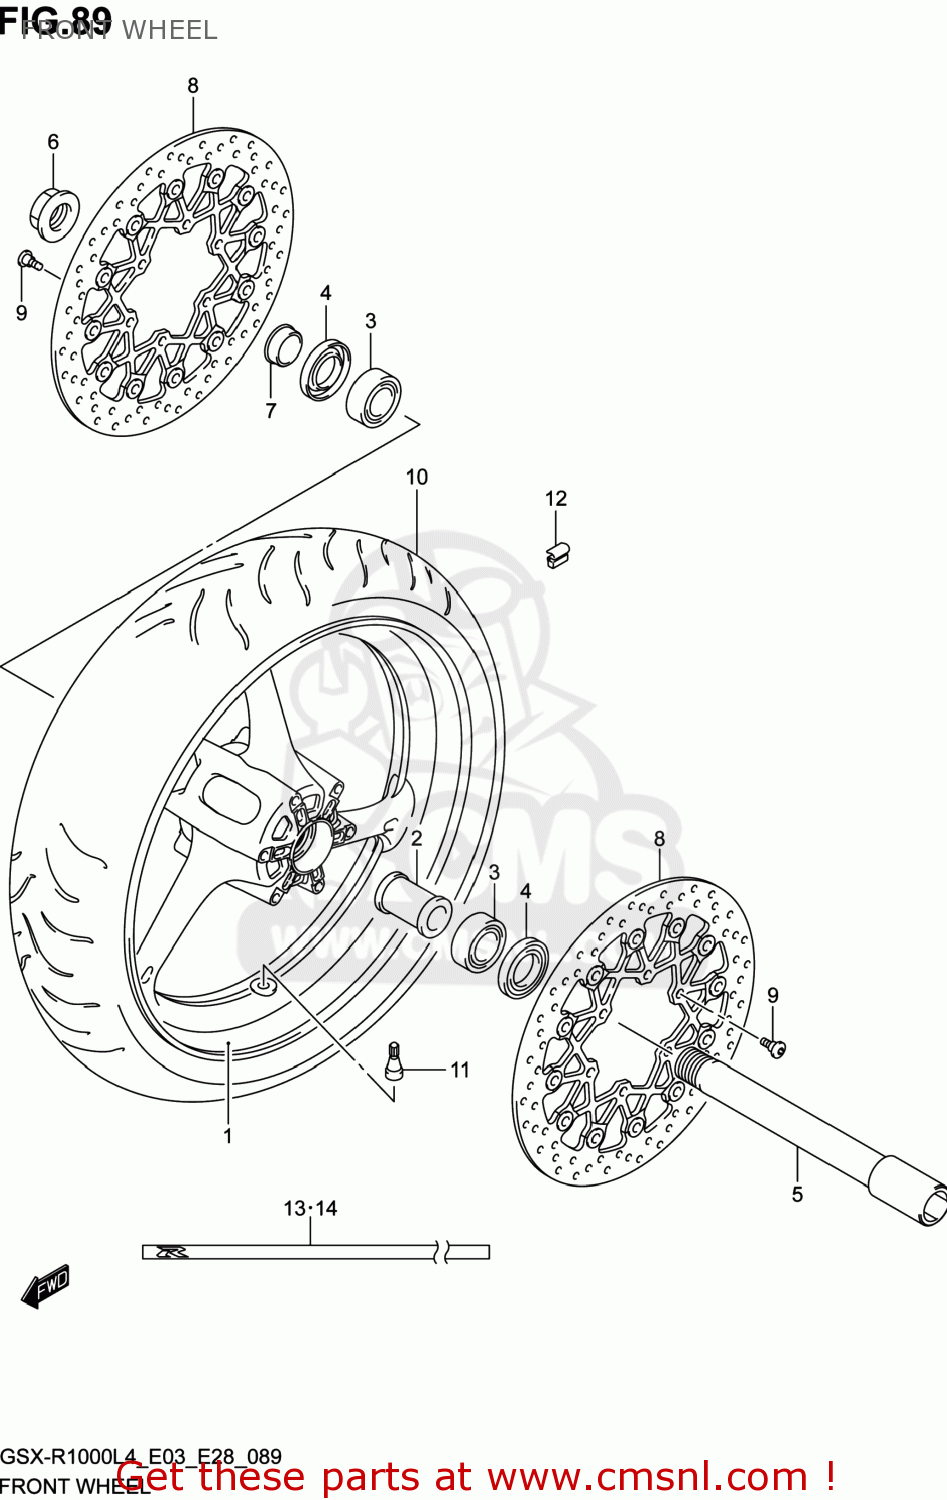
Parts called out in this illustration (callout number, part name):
1	WHEEL,FR(17M/CXMT3.50)
2	SPACER,FR HUB BEARING
3	BEARING(25X52X15)
4	SEAL,OIL(32X52X7)
5	AXLE,FR
6	NUT,FR AXLE
7	SPACER,FRONT A
8	DISC,FR BRAKE
9	BOLT(6X21)
10	TIRE,FR
11	VALVE ASSY,WHEEL RIM(TR412)
12	BALANCER,WHEEL(10G)
13	TAPE,WHEEL FRONT,R
14	TAPE,WHEEL FRONT,L
